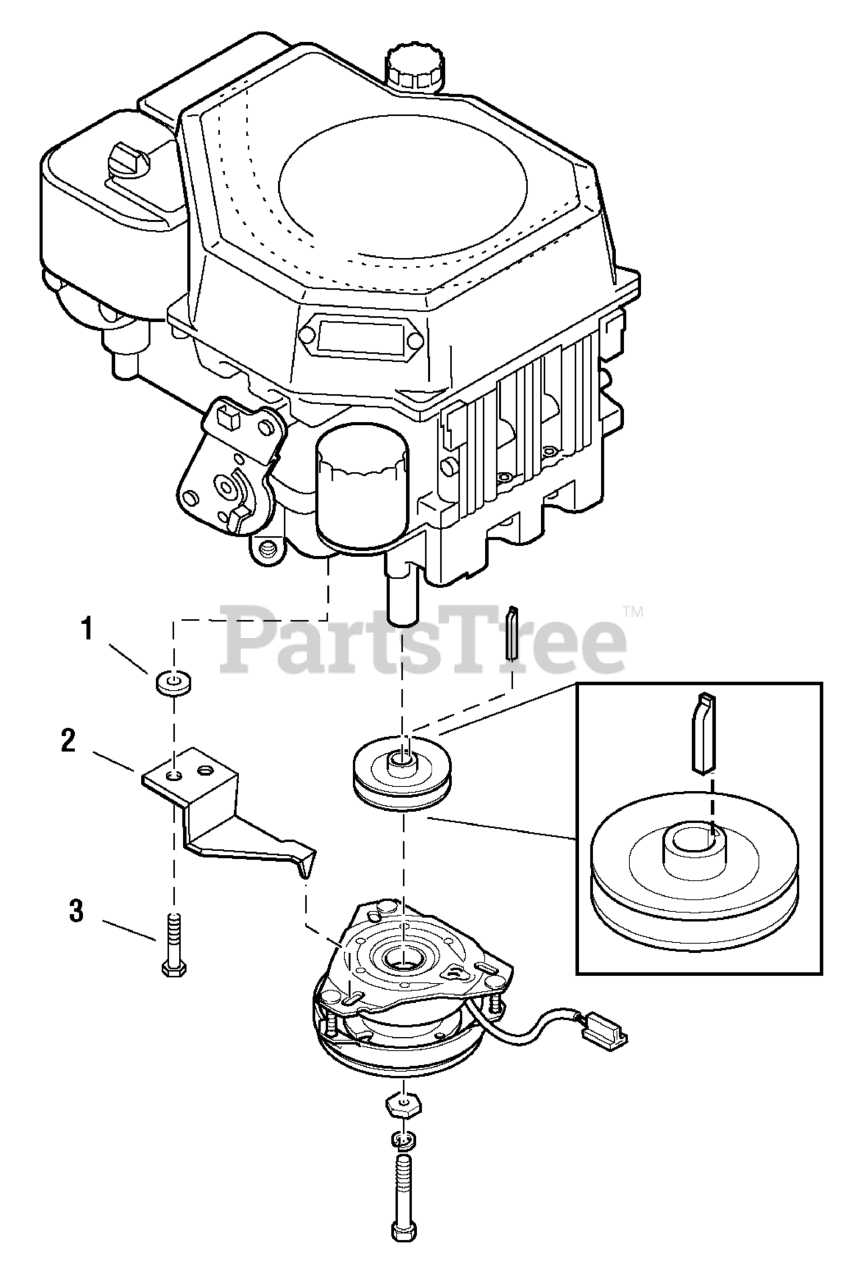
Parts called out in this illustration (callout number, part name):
1	WASHER
2	ANCHOR, Clutch
3	*CAPSCREW, 3/8-16 x 1-1/4
